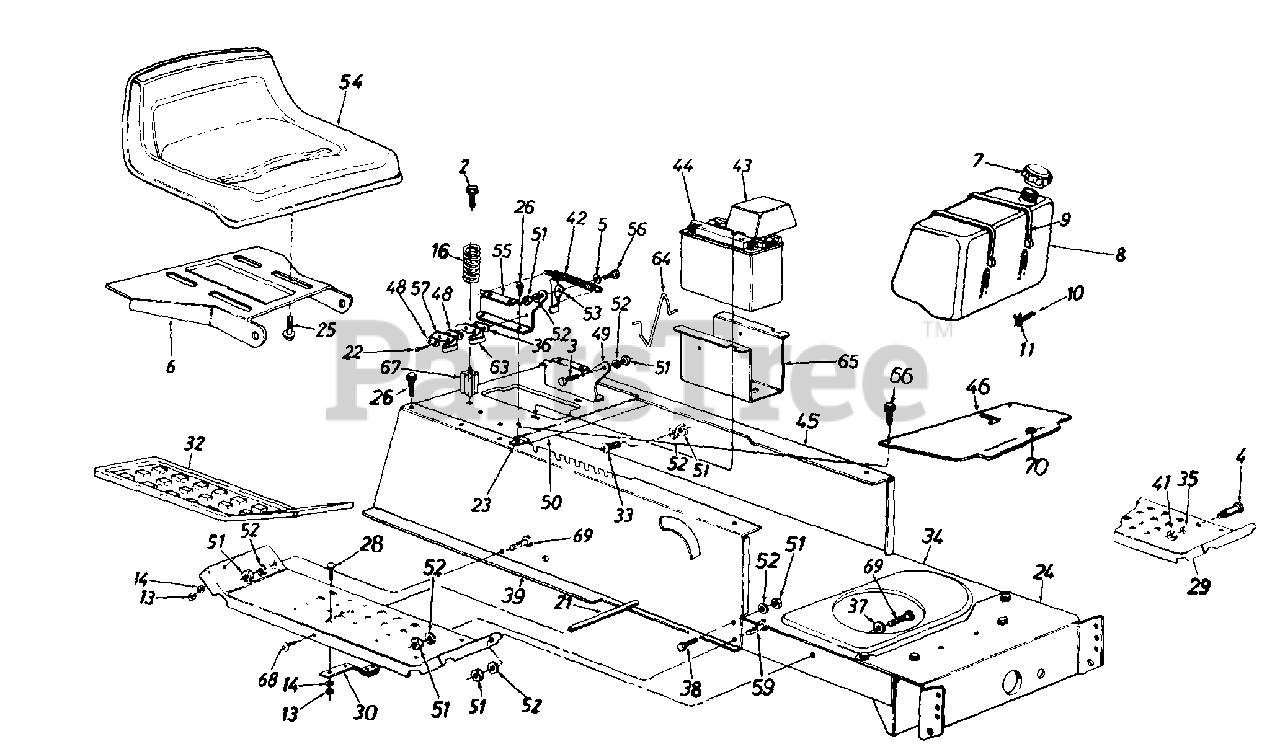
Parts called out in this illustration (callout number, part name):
2	Hex Wash. Hd. Tap Scr. 5/16-18 x 3.25" Lg.
3	Shld. Bolt .437" Dia. x .162"
4	Shld. Bolt .50" Dia. x .84"
5	Spr-Wash. .445" I.D. x .75
7	Fuel Cap
8	Fuel Tank (12.5 H.P. & Smaller)
9	Tie Strap
10	Fuel Line
11	Hose Clamp
13	Hex Nut 1/4-20 Thd.
14	L-Wash. 1/4" I.D.
16	Compression Spring
21	Running Board Rod
22	Hex Wash. Hd. AB-Tap Scr. 08 x .50" Lg.
23	Speed Nut #10Z
25	Hex Tap Scr. 3/8-16 x .75"
26	Hex Wash. Hd. AB-Tap Scr. 5/16 x .75" Lg.
28	Carriage Bolt 1/4-20 x .62"
32	Rubber Foot Pad - L.H.
33	Truss Mach. Scr. 5/16-18 x .75" Lg.
36	Insulator Boss Plate
37	Fl-Wash. .344" I.D. x .625" O.D.
38	Hex Bolt 5/16-18 x .75" Lg.
42	Extension Spring 5.31" Lg.
43	Battery Cover
44	12-V Battery
52	L-Wash. 5/16" I.D.
53	Seat Lift Brkt.
54	Seat 8-7/8" High
56	Shld. Bolt .437" Dia. x .268"
57	Spring Switch
59	Hex Wash. TT-Tap Scr. 5/16-18 x 7/8" Lg.
63	Safety Switch (Seat)
64	Battery Tray Clip (Single Cylinder)
65	Battery Tray
66	Truss Mach. B-Tap Scr. #10 x .5" Lg.
67	Spring Spacer
68	Pan Hd. Cutting Scr. 5/16-18 x .75" Lg.
69	Hex Bolt 5/16-18 x .75" Lg.
70	Snap Bushing
